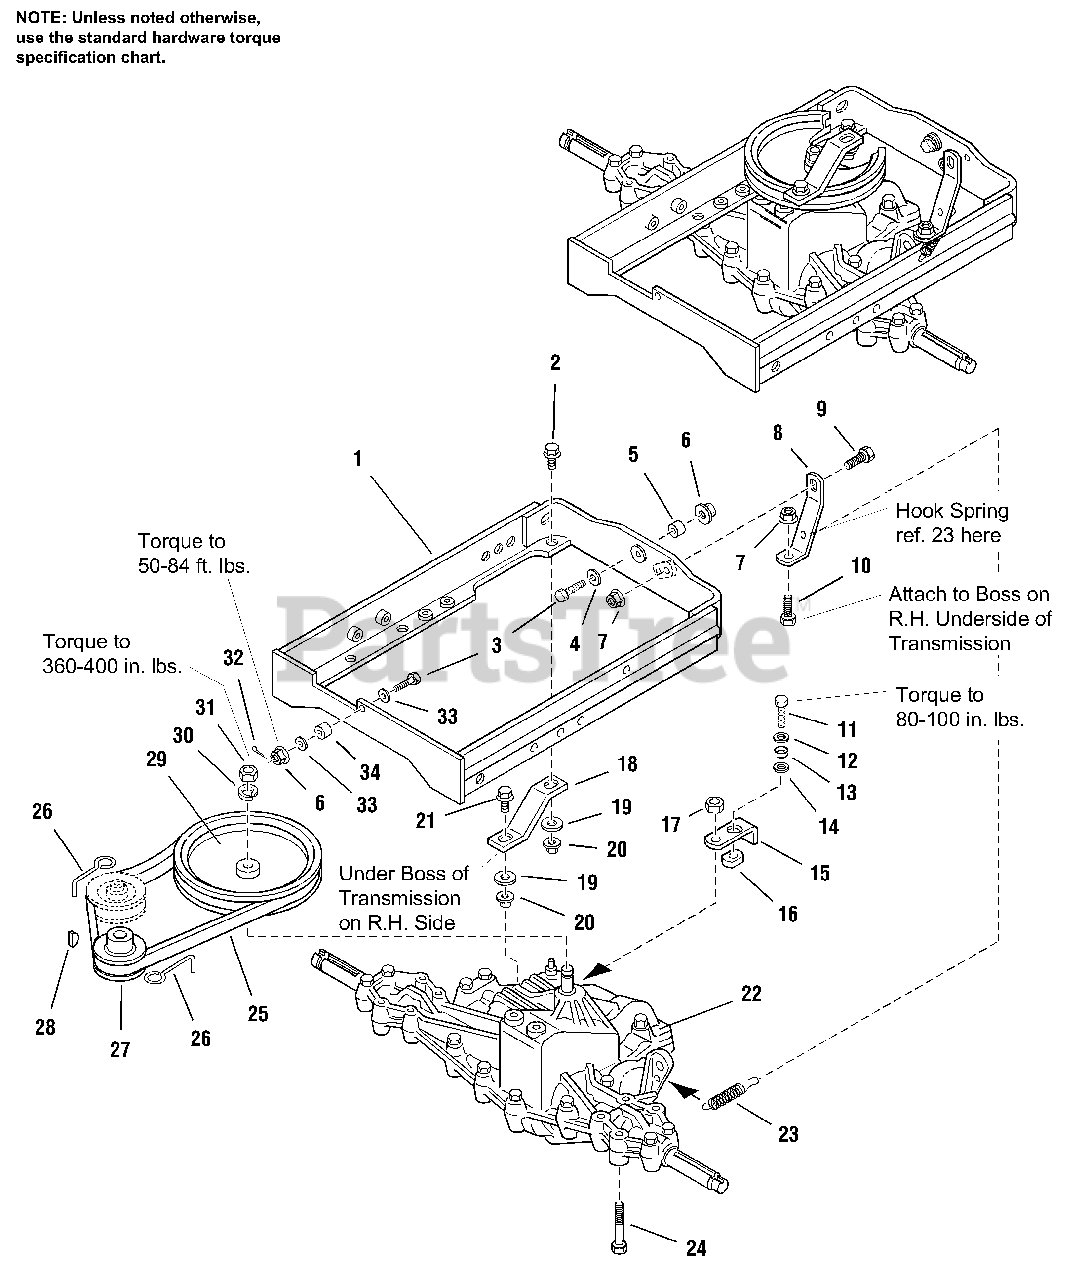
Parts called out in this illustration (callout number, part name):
1	CARRIER ASSY.
2	SCREW, Hex, Whizlock, 5/16-18 x 3/4
3	CAPSCREW, Hex Hd., 1/2-13 x 1-1/4
4	WASHER, Plain, 17/32 x 1-1/4 x 5/64
5	BUSHING, Rear
6	NUT, Hex, Flange Lock, 1/2 x 13
7	NUT, Hex, Flange Whiz, 5/16-18
8	STRAP, Torque
9	CARRIAGE BOLT, 5/16-18 x 5/8
10	CAPSCREW, Hex, 5/16-18 x 2-1/4
11	SCREW, Taptite, #10-24 x 1-1/4
12	WASHER, Plain, 1/4 x 1-1/4 x 5/64
14	WASHER, Plain, 13/32 x 1-1/4 x 1/16
15	LEVER, Release
17	NUT, Hex, Lock, 1/4-20
18	STRAP, Torque
19	WASHER, 5/16
20	NUT, Flange, 2-Way Lock, 5/16-18
21	SCREW, Hex, Whizlock, 5/16-18 x 1-1/2
22	TRANSMISSION, Hydro
23	SPRING, Return
24	SCREW, Taptite, 5/16-18 x 2-1/4
27	PULLEY, Engine
28	KEY, Hi-Pro
29	PULLEY, Transmission
30	LOCKWASHER, 1/2
31	NUT, Hex, Jam, 1/2-20
32	COTTER PIN, 1/8 x 1-1/2
33	WASHER, Belleville, 1/2
34	BUSHING, Front
